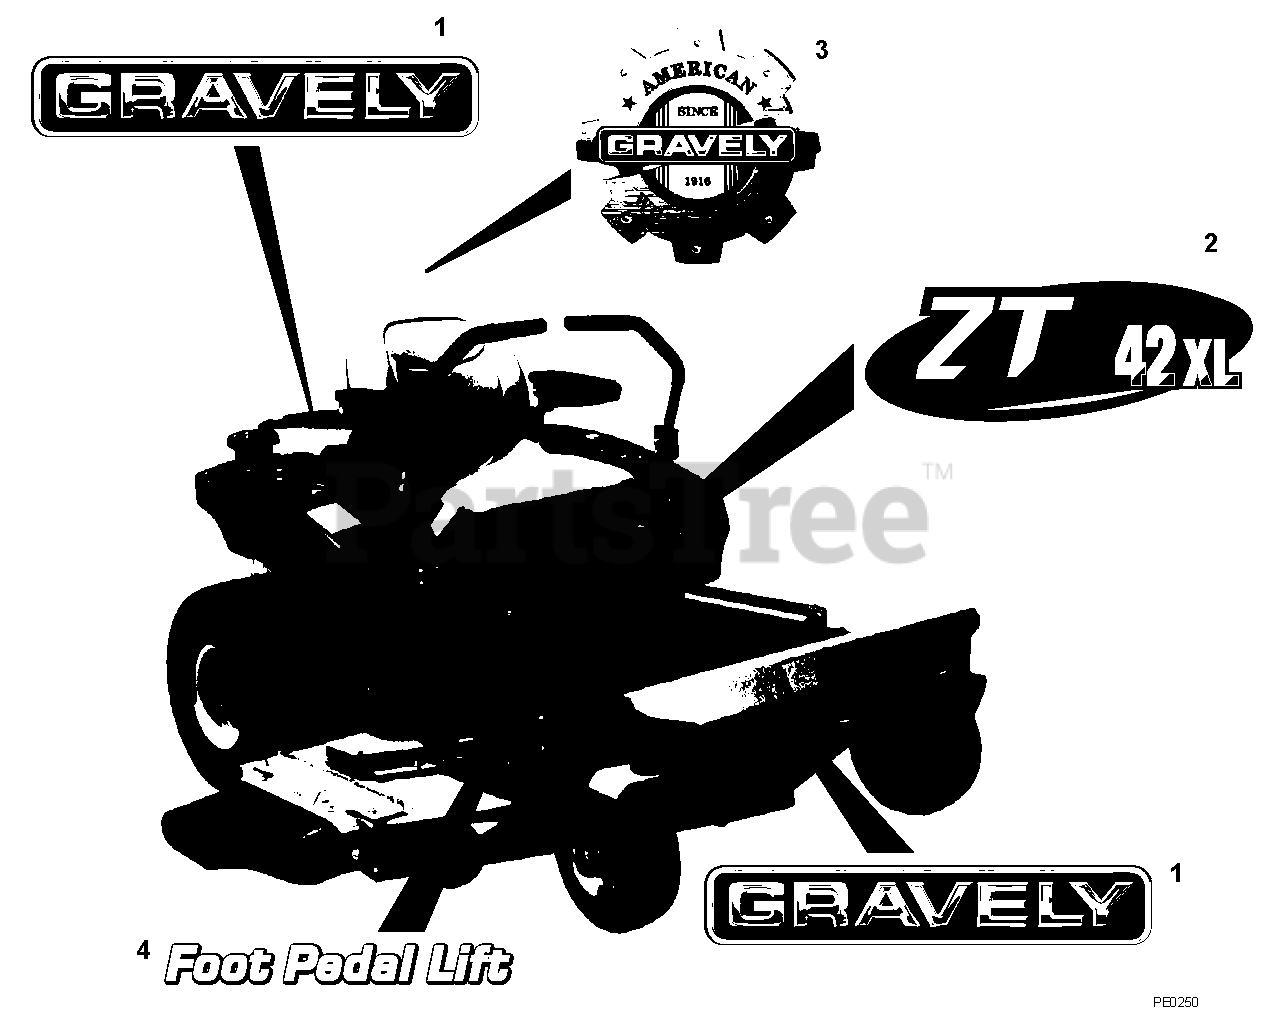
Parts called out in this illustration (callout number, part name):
1	Decal, Gravely Logo
2	Decal, 42 ZT XL
2	Decal, 48 ZT XL
2	Decal, 54 ZT XL
3	Decal, Gravely American Heritage
4	Decal, Foot Pedal Lift
